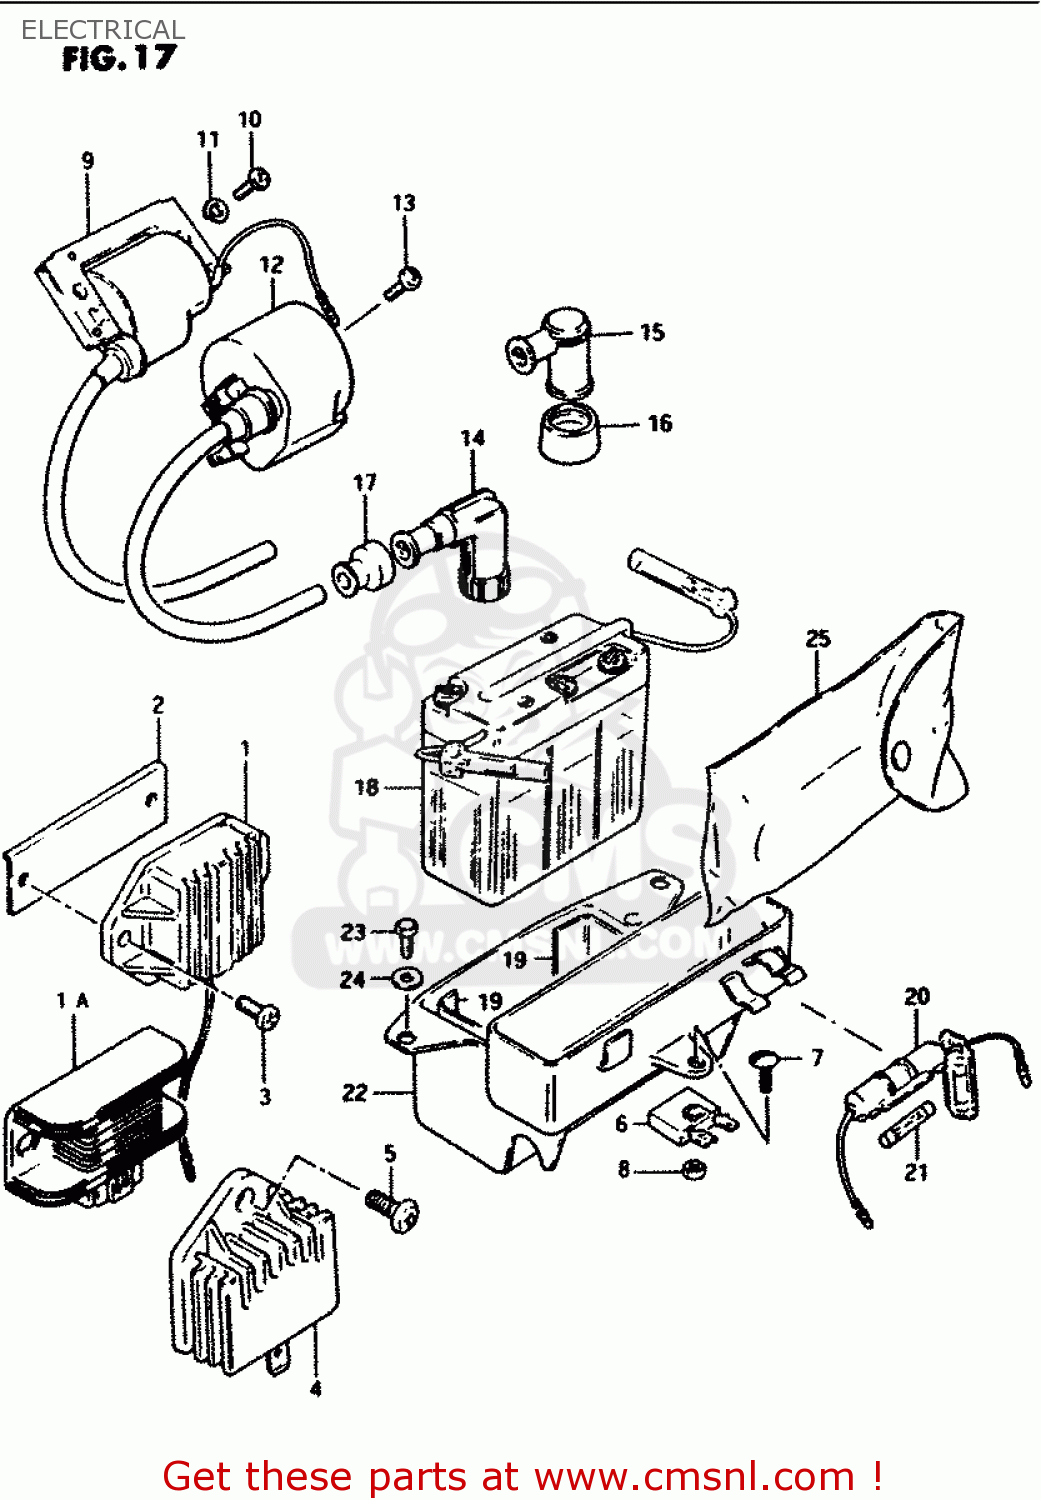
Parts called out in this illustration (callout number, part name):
1	REGULATOR ASSY, VOLTAGE
1A	RECTIFIER ASSY
2	PLATE, REGULATOR
3	SCREW
4	REGULATOR ASSY,VOLTAGE
5	SCREW
6	RECTIFIER ASSY
7	SCREW(5X18)
8	NUT 5MM
9	COIL ASSEMBLY,IGNITION
10	SCREW
11	WASHER,LOCK
12	COIL ASSEMBLY,IGNITION
13	SCREW
14	CAP,SPARK PLUG
15	CAP ASSY,SPARK PLUG
16	SEAL,SPARK PLUG
17	SEAL,HIGH TENSION CORD
18	BATTERY(6N4B-2A,6V4.2AH)
19	PROTECTOR,20X9
20	CASE ASSY,FUSE
21	FUSE(10A)
22	HOLDER, BATTERY
23	BOLT
24	WASHER(6.5X16X1.2)
25	TOOL ASSY
